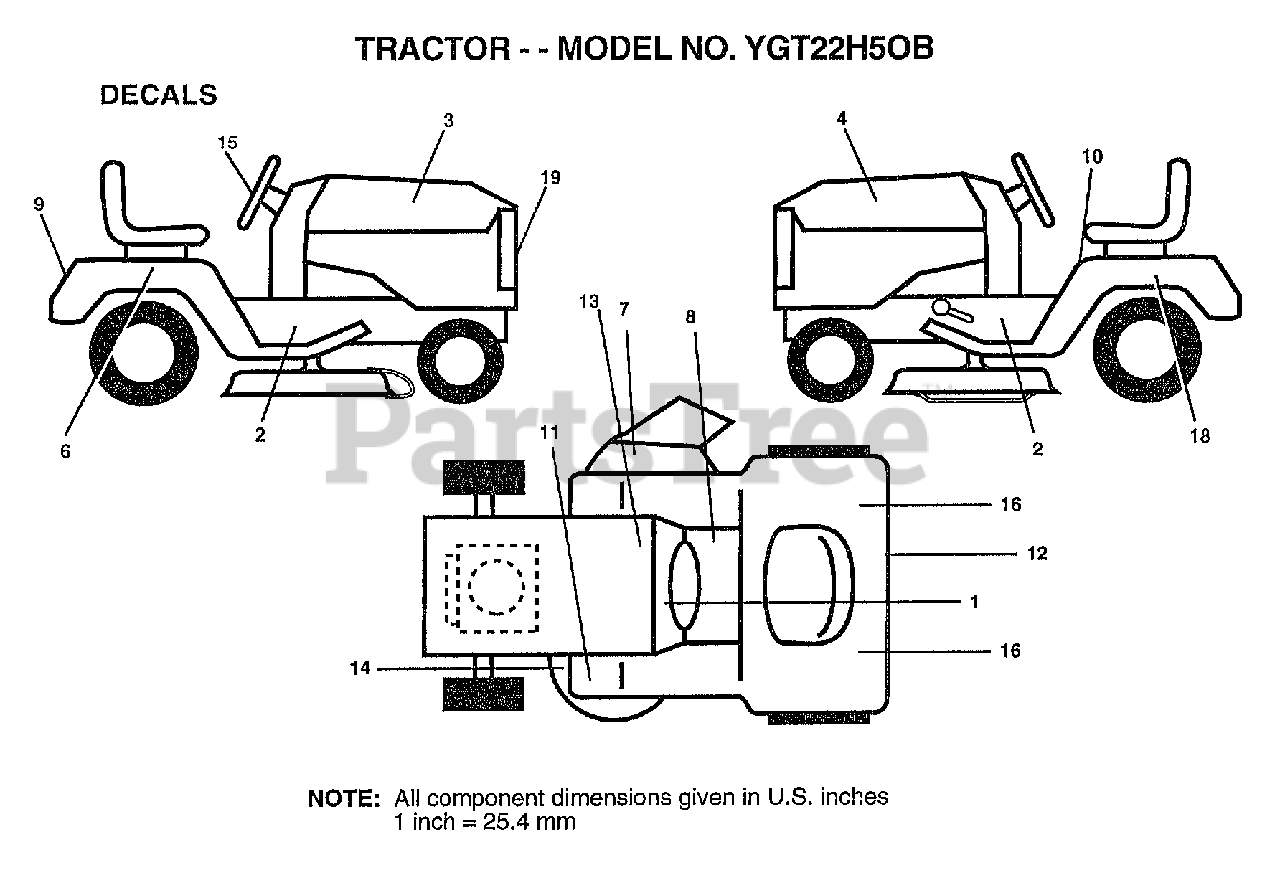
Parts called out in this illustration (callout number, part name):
1	DECAL OPER INSTR.
2	DECAL, CHASSIS 50"
3	"DECAL HOOD,RH"
4	DECAL HOOD LH
6	DECAL FENDER RH
7	"DECAL, WARNING"
8	DECAL BRAK PARK
9	DECAL FENDER
10	DECAL.CAUT.ENG/FR
11	DECAL T
12	DECAL D-BAR CNTRL
13	DECAL.BATRY.3-3908
15	DECAL INS STRG WH
16	REFLECTOR-TAIL YT
18	DECAL FENDER LH
19	DECAL GRILLE
